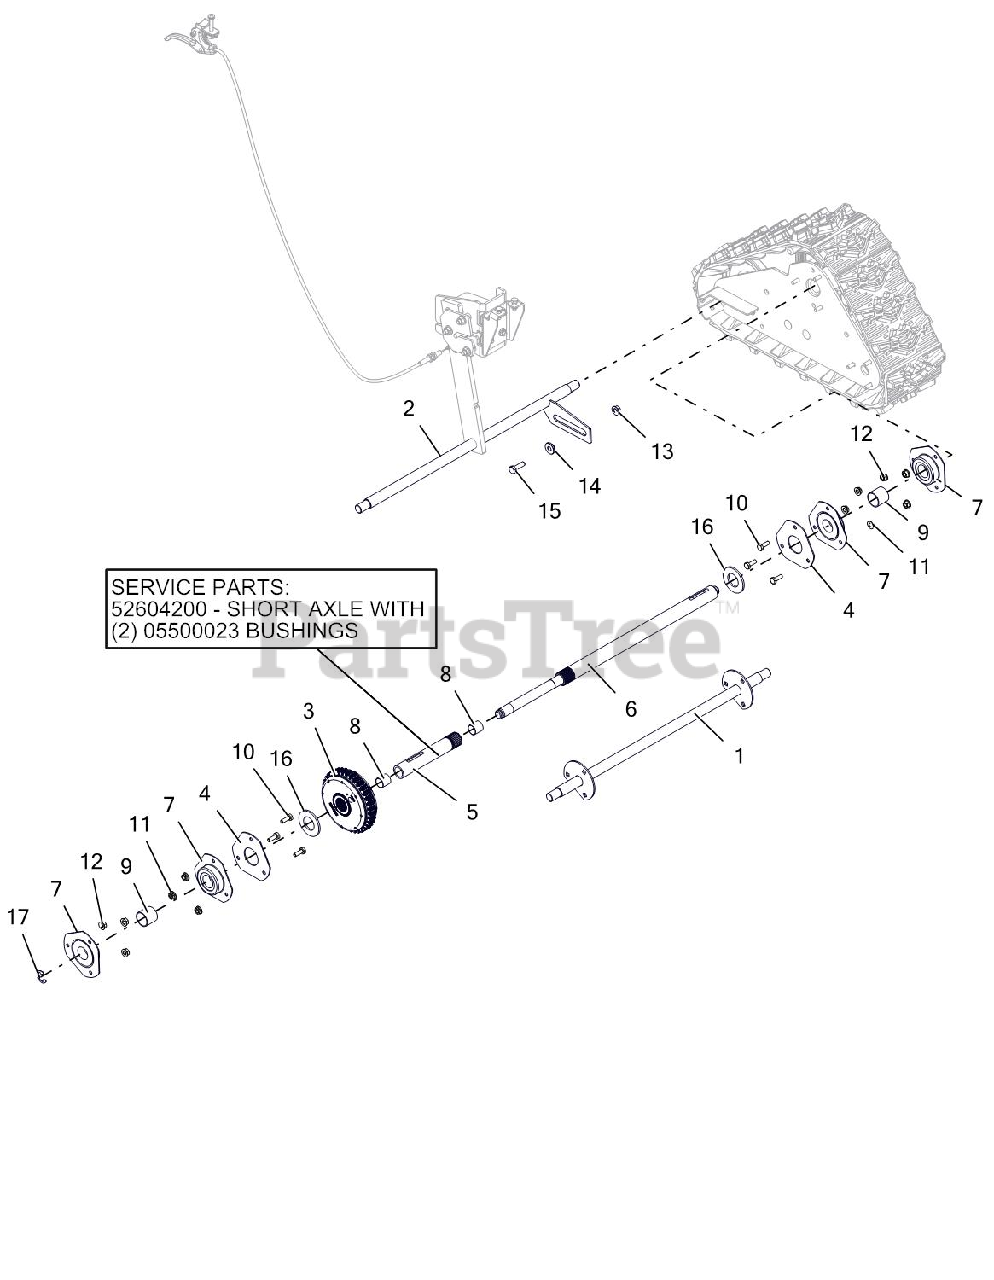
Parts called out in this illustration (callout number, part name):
1	AXLE, FRONT - PRO
2	AXLE, REAR - PRO TRACK
3	DIFFERENTIAL, AUTOMATIC
4	PLATE, BEARING SPACER
5	BSHG-SLV .706X.764X.75 BRZ
5	AXLE, SHORT-TRACK DIFFERENTIAL
5	AXLE, SHORT-TRACK W/BUSHINGS
6	AXLE, LONG-PRO AUTO DIFF
7	BRG-FLG 1.003/1.000 3 BOLT
8	BSHG-SLV .706X.764X.75 BRZ
9	BSHG-SLV, 1.012X1.125X1.00
10	@BLT-HEX .25-20X.75 GR5 YWZC
11	@NUT-LK-CTR-FLG .25-20 YWZC
12	@NUT-LK-TOP-FLG .25-20 YWZC
13	@NUT-LK-TOP-FLG .31-18 YWZC
14	BSHG-FLG .325X.499X.3X.875
15	@BLT-HEX .31-18X1.00 GR5 YWZC
16	WSHR-FL-STL- 1.062X2.0X.134 YZ
17	RG-RTNG-EXT .625X.042
